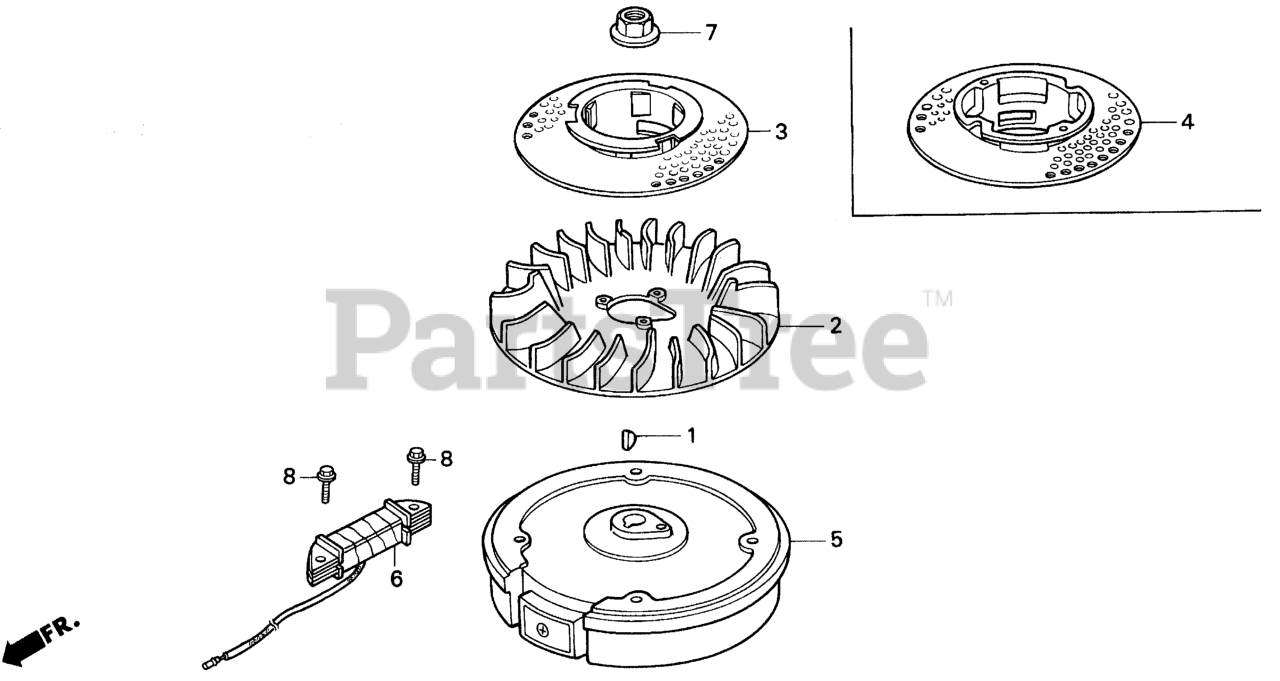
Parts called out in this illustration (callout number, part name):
1	KEY, SPECIAL WOODRUFF (25X18)
2	FAN, COOLING (USA)
3	PULLEY, STARTER
4	PULLEY, STARTER
5	FLYWHEEL (STARTER MOTOR)
5	FLYWHEEL
6	COIL ASSY., CHARGE
7	NUT, SPECIAL (14MM)
8	BOLT, FLANGE (6X28)
